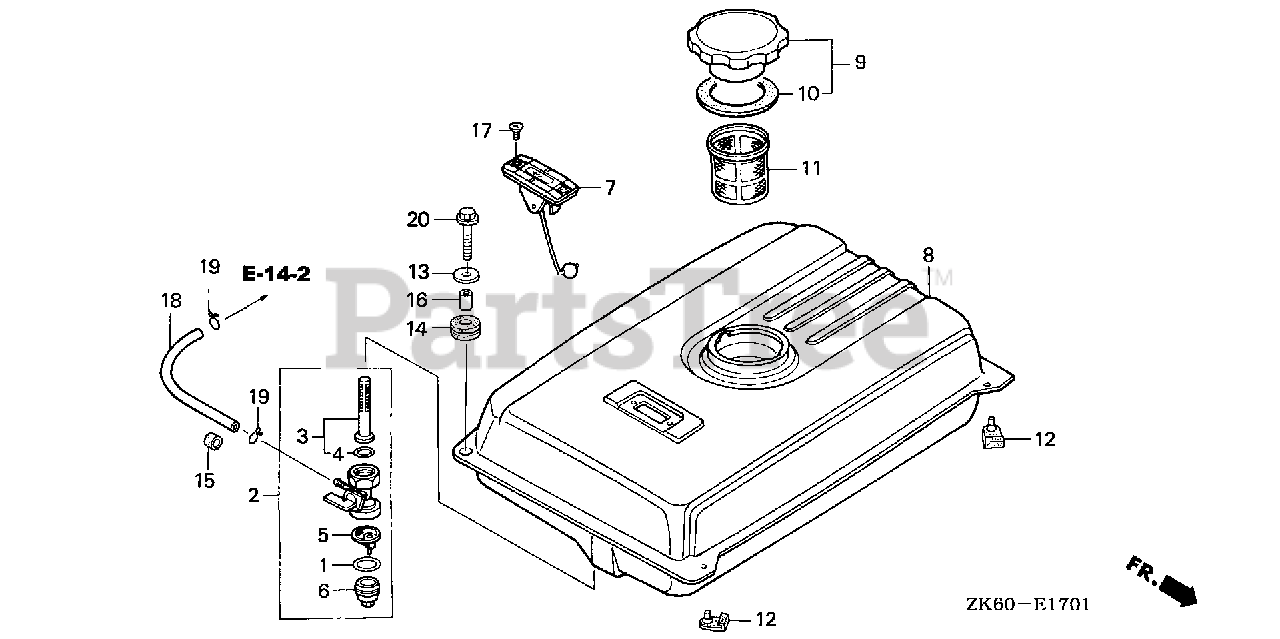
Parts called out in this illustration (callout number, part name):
1	GASKET, FUEL STRAINER CUP
2	PETCOCK ASSY.
3	SCREEN SET, FUEL STRAINER
4	O-RING (9.0X1.3)
5	FILTER, CUP
6	CUP, FUEL STRAINER
7	METER ASSY., FUEL
8	TANK, FUEL *NH31* (MCKINLEY WHITE)
8	TANK, FUEL *NH1* (BLACK)
8	TANK, FUEL *T68* (TSURUMI BLUE)
8	TANK, FUEL *Y131* (LIGHTNING YELLOW)
8	TANK, FUEL *R280* (POWER RED)
8	TANK, FUEL *T80* (BAKERITE ORANGE)
9	CAP, FUEL FILLER
10	GASKET, FUEL FILLER CAP
11	FILTER, FUEL
12	RUBBER, TANK MOUNTING
13	WASHER, TANK CUSHION
14	RUBBER, TANK CUSHION
15	RUBBER, FUEL (9X15X10)
16	COLLAR, TANK CUSHION
17	SCREW, FLAT (5X10)
18	BULK HOSE, FUEL (4.5X3000) (4.5X150)
18	BULK HOSE, FUEL (4.5X3000) (4.5X190)
19	CLIP, TUBE (B8)
20	BOLT, FLANGE (6X22)
